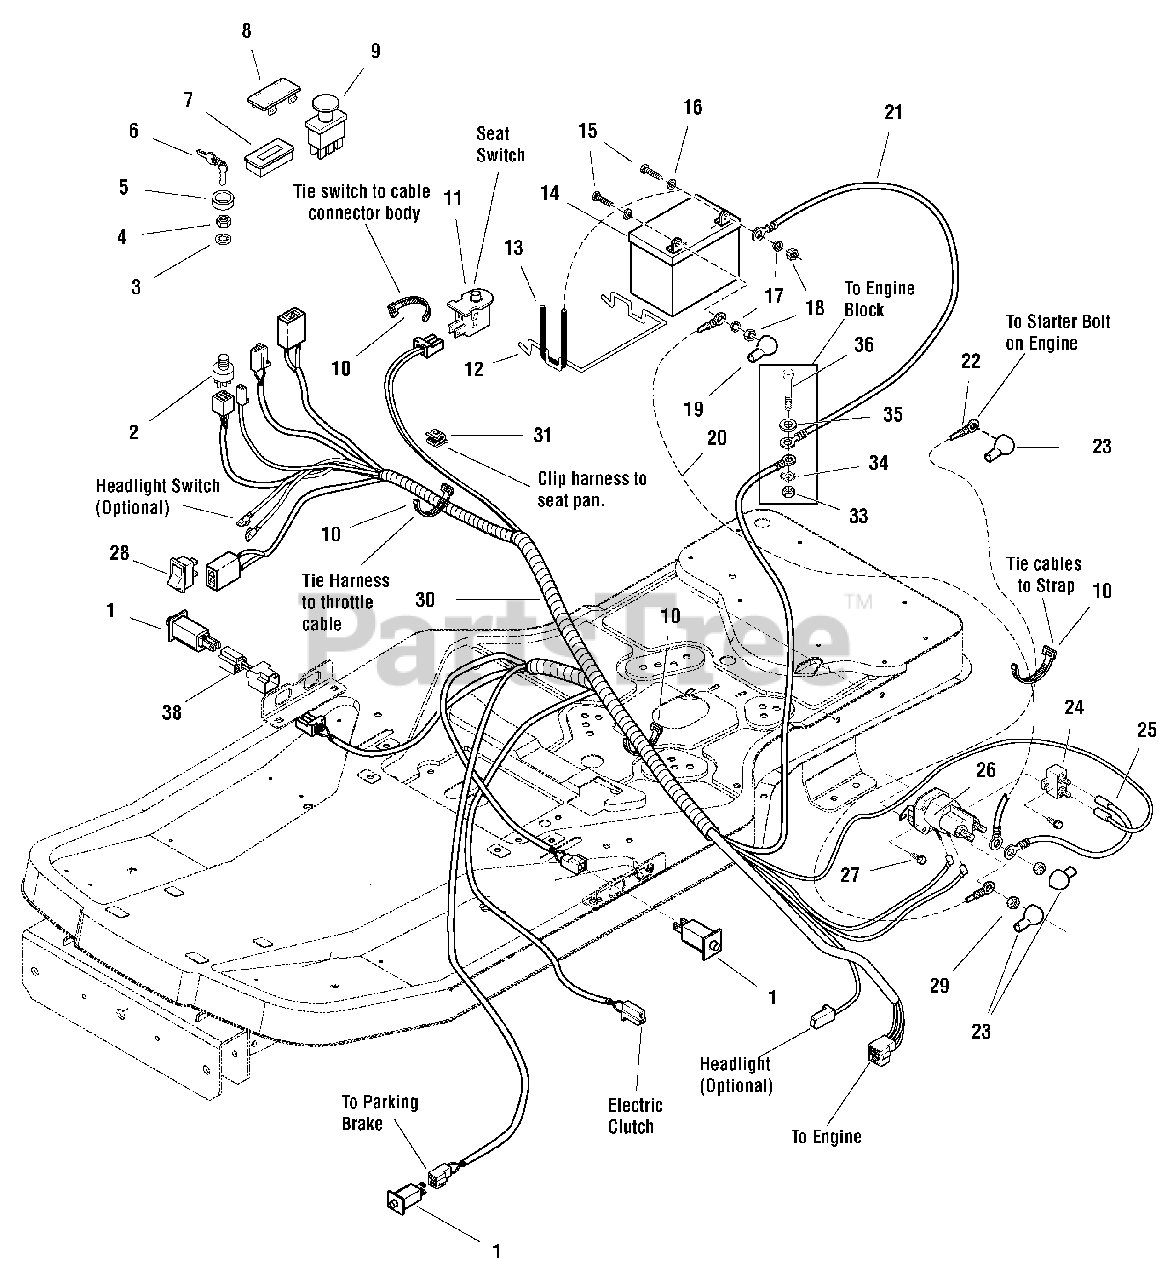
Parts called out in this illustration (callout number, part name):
1	SWITCH, Push Button
2	SWITCH ASSEMBLY, Ignition, 5/8-32 6 Pin Indak
3	LOCKWASHER, Internal Tooth, 5/8 Thin
4	NUT, Hex Flange, 5/8-32 IGN SW Die Cast
5	COVER, Ignition Switch
6	KEYS
7	HOUR METER, No Alarms
9	SWITCH, PTO Push/Pull Symbols
10	TIE, Self Locking
11	SWITCH, Seat
12	BRACE, Battery, .19 DIA Wire
13	STRAP, Black Rubber, .19 SQ 7.88 OD Battery
14	BATTERY, 12 Volt 6 Cell 230 CCA
15	CAPSCREW, Hex Head, 1/4-20 x 3/4, G5
16	WASHER, 1/4, .27 ID x .62 OD x .05 THK
17	LOCKWASHER, Spring, 1/4
18	NUT, Hex, 1/4-20 NC-2B
19	BOOT, Insulator, Red PVC Warning
20	CABLE, # 6 x 10 LG, Red Two-Ring Terminals
21	CABLE, # 6 X 26 LG, Two-Ring Terminals
22	CABLE, # 6 x 15 LG, Two-Ring Terminals
23	COVER, Terminal Red PVC
24	BREAKER, Circuit, 12 Volt 20 AMP
25	WIRE, 12 Gauge, 7.9 LG
26	SOLENOID, Two Terminals, Trombetta
27	SCREW, Hex Washer Head Taptite, 1/4-20 x 1/2
28	SWITCH, Electric Height of Cut
29	NUT, Hex Keps, 5/16-24
30	HARNESS, Wiring
31	CABLE, Clip
33	NUT, Hex Whiz Lock Flange, 5/16-18
34	LOCKWASHER, External Tooth, 3/8
35	WASHER, 5/16, .34 ID x 3/4 OD x .06 THK
36	CAPSCREW, Hex Head, 5/16-18 x 2
38	WIRING ASSEMBLY, Jumper All Conditions Shutdown
